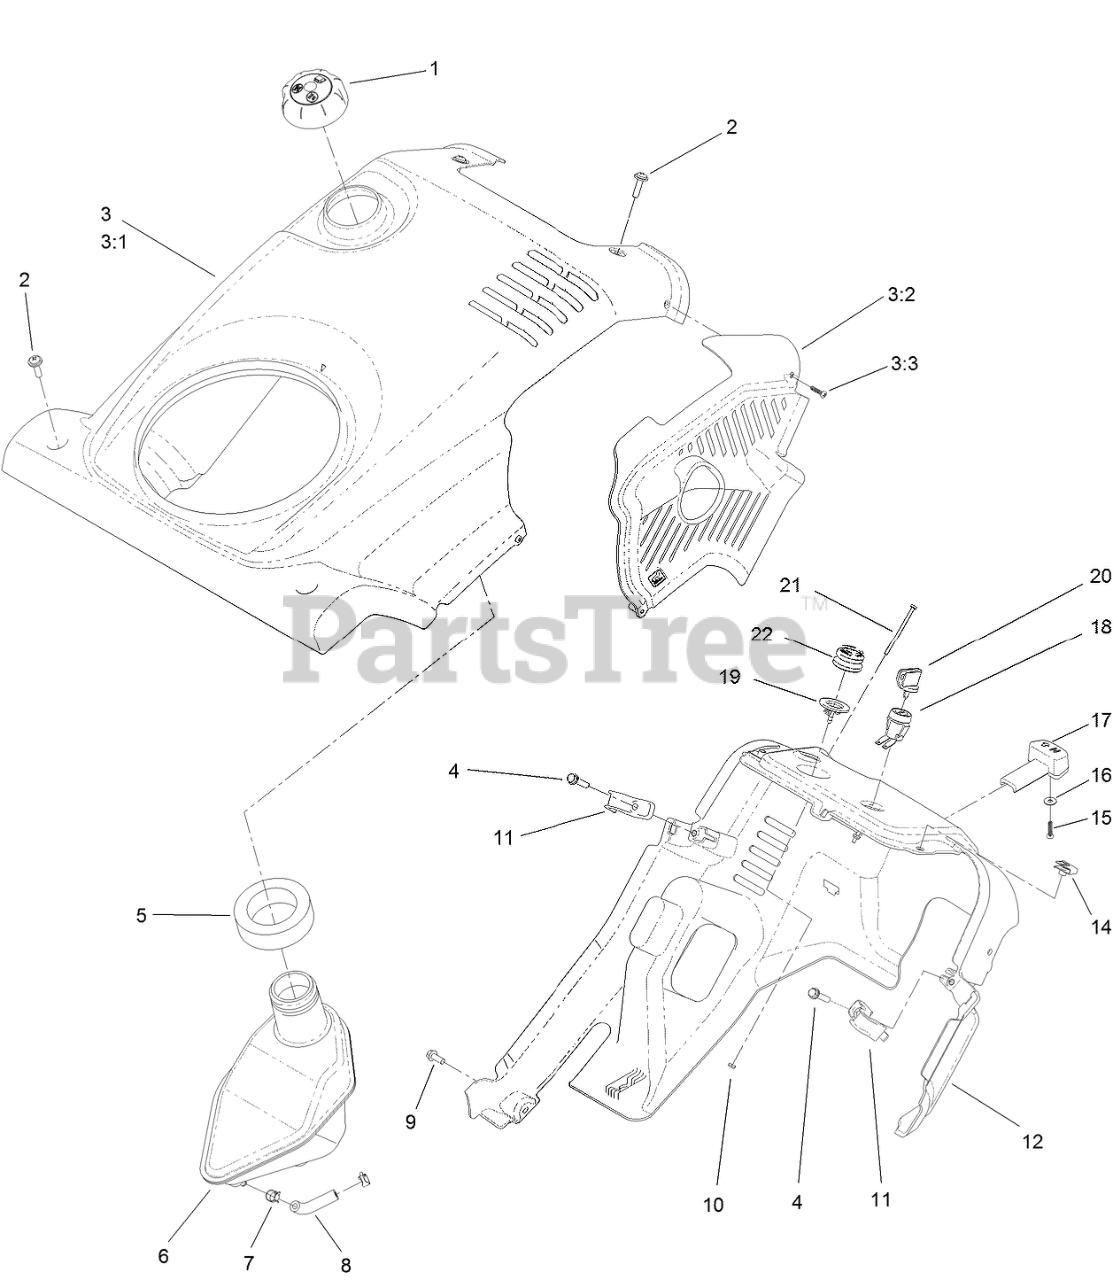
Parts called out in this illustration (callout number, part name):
1	CAP-GAS
2	SCREW-PPH
3	SHROUD ASM
3:1	SHROUD
3:2	BAFFLE-EXHAUST
3:3	SCREW-PPH
4	SCREW-PLASTITE
5	SEAL-TANK
6	TANK-FUEL, GAS
7	CLAMP-HOSE
8	HOSE-FUEL
9	SCREW-HWH
10	NUT-HEX
11	CLIP-SHROUD
12	SHROUD-LOWER
15	SCREW-PPH
16	WASHER-PLAIN
17	KNOB-CHOKE
18	SWITCH
19	BODY-PRIMER
20	KEY-IGNITION
21	SCREW-HWH
22	BULB-PRIMER
